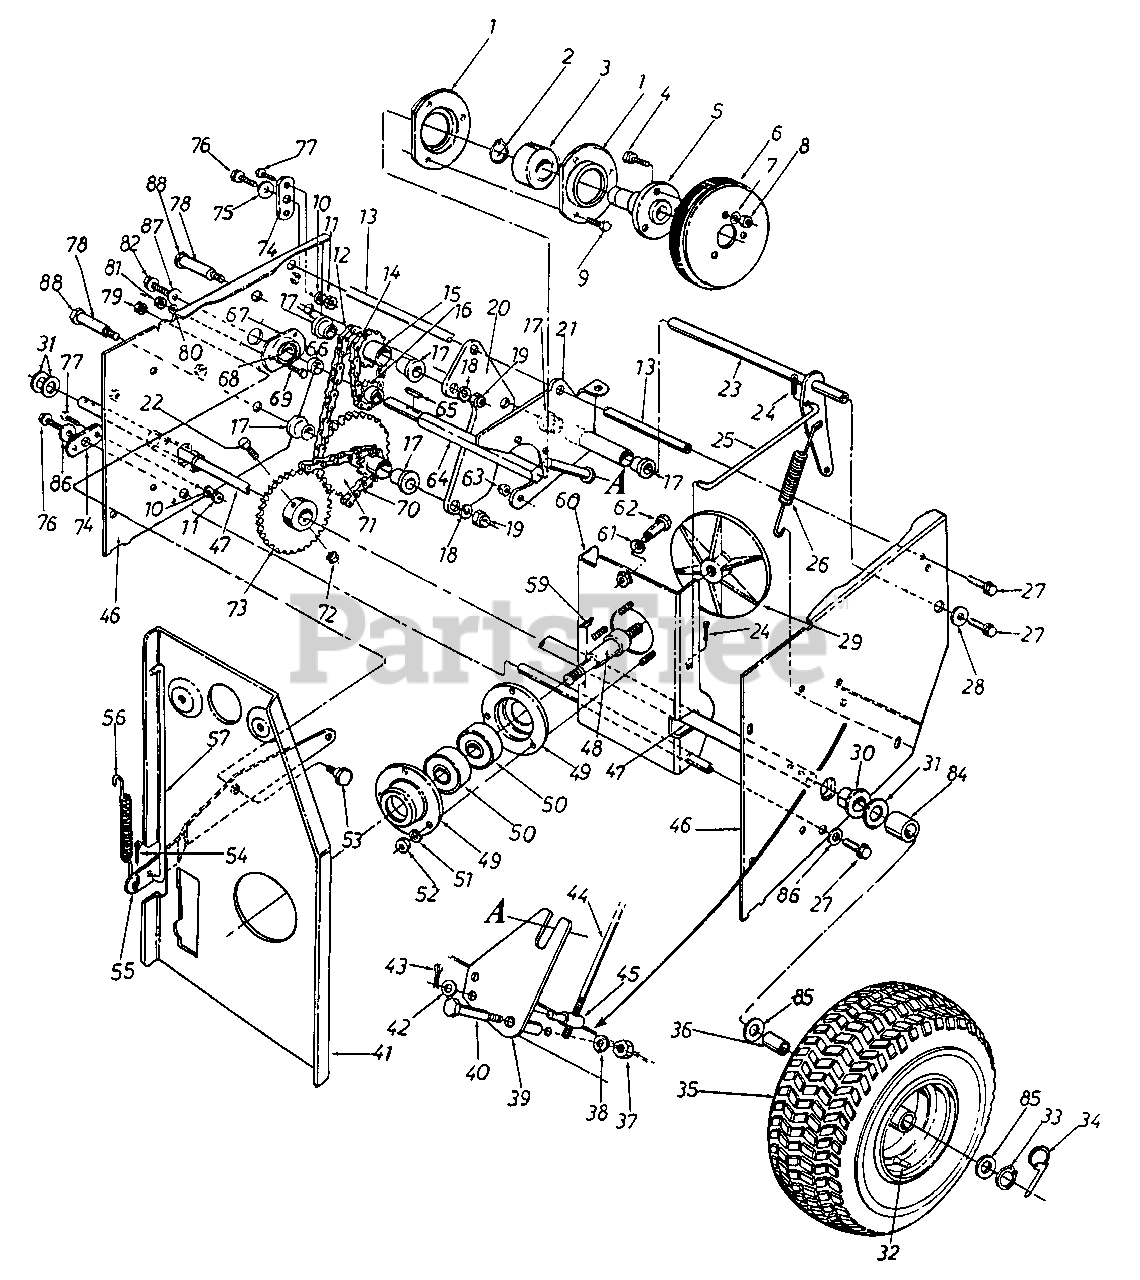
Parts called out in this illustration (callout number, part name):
1	HOUSING-BRG
2	RING-SNAP FOR 1.00 DIA SHAFT
3	RING-SNAP FOR 1.00 DIA SHAFT
4	SCREW-HEX SEMS 5/16-18 x .75
5	ADAPTER-FRICTION WHL
6	WHEEL ASSY-FRICTION
7	WASHER-LOCK-5/16
8	NUT-HEX 5/16-18
9	SCREW-HEX 1/4-28 x .62
10	LOCK WASHER 1/4 DIA
11	NUT-HEX 1/4-20
12	NUT-ACORN LOCK
13	AXLE-SLIDING SUP
14	#41 CHAIN 1/2 PITCH x 19 LINKS
15	SPROCKET & HUB ASSY-9 & 147
16	SPROCKET-CENTER #41-8T
17	BEARING-FLANGE .630 ID
18	NUT-HEX INS L-3/8-24
19	NUT-HEX INS L-3/8-24
22	SCREW-HEX
23	BRACKET ASSY-DR CLUTCH
24	PIN-INTERN COT-5/16 DIA
25	ROD-CLUTCH-DR
26	SPRING-IDLER EXTN
27	SCREW-HEX 5/16-18 x .62
28	WASHER-FL-.344 x .62
29	PLATE-ALUM DRIVE
30	BEARING-FLANGE W/FLATS
31	WASHER-FL
32	VALVE-TUBELESS AIR
33	PIN-CLICK-5/16 DIA x 1.75LG
34	PIN-CLICK-5/16 DIA x 1.75LG
35	WHEEL ASSY W/TIRE
36	BEARING-SLEEVE
37	NUT-HEX JAM 3/8-18
38	WASHER-LOCK-3/8
41	BRACKET ASSY-ENG
42	WASHER-FL-.344 x .62
43	PIN-COTTER-3/32 DIA x .75
44	ROD-SHIFT
45	FERRULE-ADJ
46	FRAME ASSY
47	AXLE-FREE WHEELING
48	SPINDLE-DRIVE PLT
49	HOUSING-BRG
50	BEARING-BALL
51	WASHER-LOCK-5/16
52	NUT-HEX 5/16-18
53	SCREW-SHLD .625 DIA x .163
54	PIN-INTERN COT-5/16 DIA
55	BRACKET-AUG CLUTCH
56	SPRING-EXTENSION
57	ROD-AUG CLUTCH
59	KEY-3/16 x 5/8
62	SCREW-SHLD .498 DIA x 1.640
63	NUT-HEX INS-L
64	SHAFT-HEX
65	KEY-HI-PRO #4-3/32X5/8 DIA-HDN
67	HOUSING-BRG
68	BEARING-BALL
69	SCREW-HEX 1/4-20 C .62
70	#420 CHAIN 1/2 PITCH x 29 LINKS
71	SPROCKET & HUB ASSY-9 & 32T
72	NUT-HEX INS-L
73	SPROCKET-22T
74	BRACKET-PIVOT AXLE
75	WASHER-FL-.344 x .62
76	SCREW-HEX 5/16-18 x .62
77	SCREW-HEX 1/4-20 C .62
78	HUB-SPROCKET
79	NUT-HEX CENTER L-3/8-16
80	LOCK WASHER 1/4 DIA
81	NUT-HEX 1/4-20
82	SCREW-HEX 5/16-18 x .62
85	WASHER-FL .794ID x 1.240 x .060
86	WASHER-FL-.344 ID x .88 OD x .063
87	WASHER-BELL .337 x .867 x .057
88	SCREW-HEX 3/8-16 x 2.75
